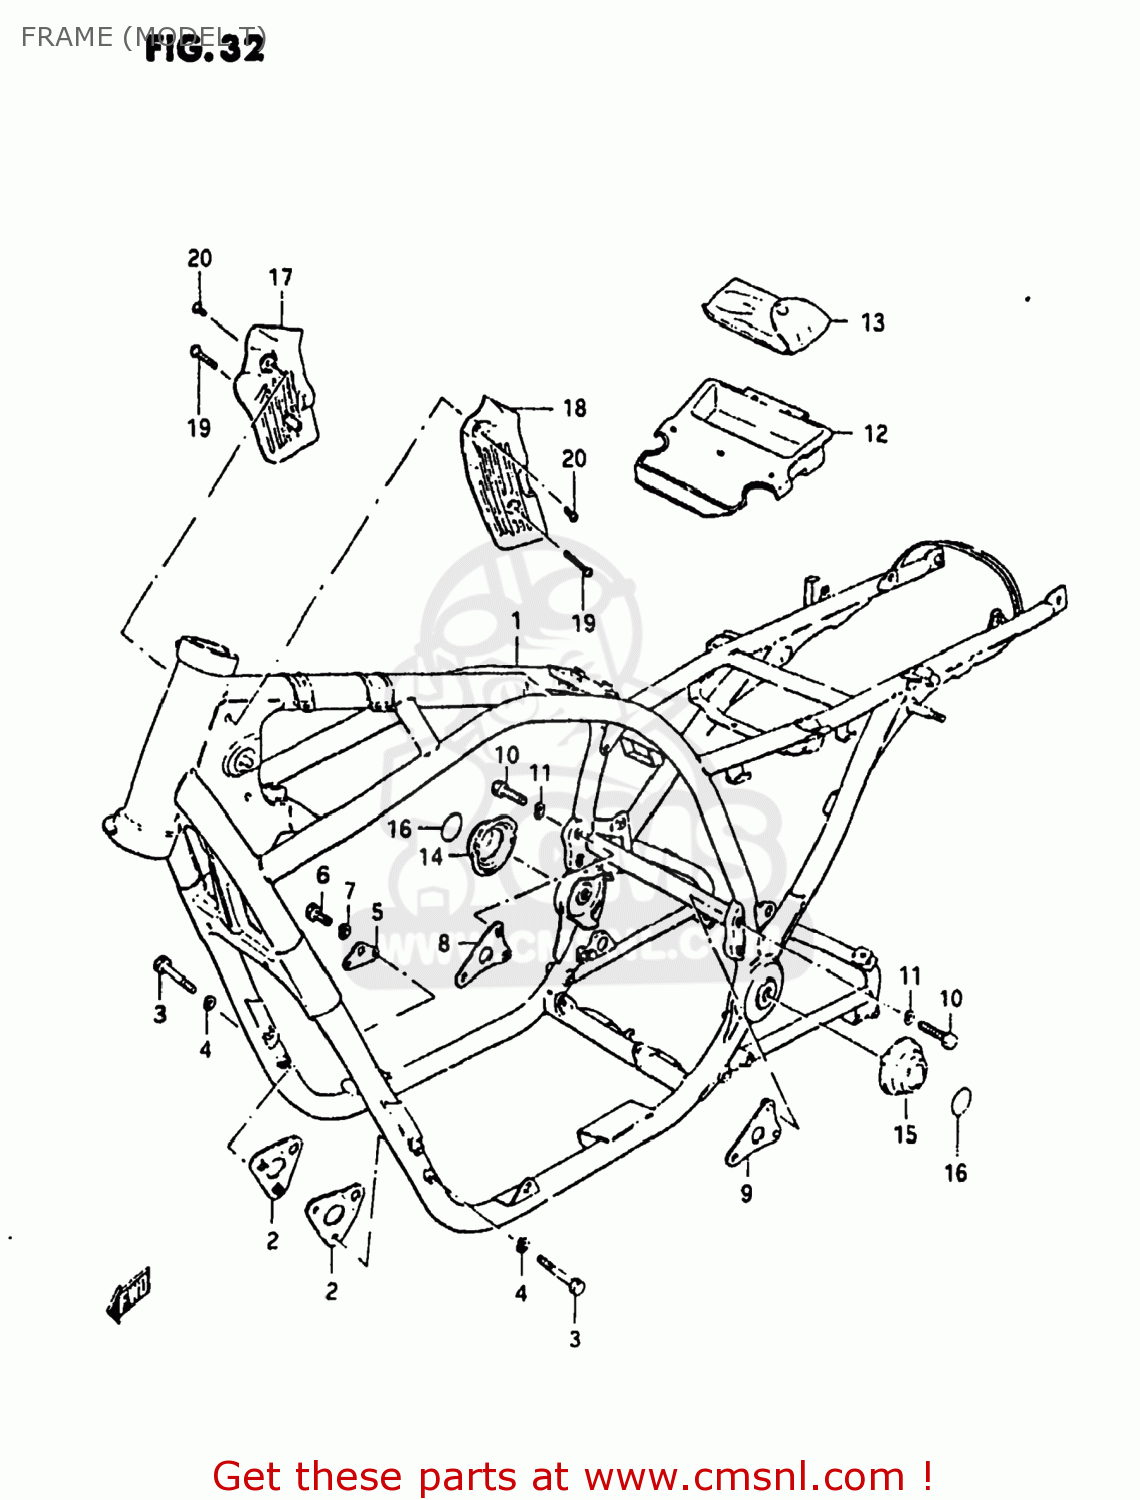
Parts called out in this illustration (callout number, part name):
1	FRAME
2	PLATE,ENGINE MOUNTING
3	BOLT
4	LOCK WASHER
5	PLATE,ENGINE MOUNTING
6	BOLT
7	LOCK WASHER
8	PLATE,ENGINE MOUNTING
9	PLATE,ENGINE MOUNTING
10	BOLT 8X40
11	LOCK WASHER
12	HOLDER,TOOL
13	TOOL SET
14	COVER,REAR SWING ARM PIVOT
15	COVER,REAR SWING ARM PIVOT
16	TAPE,REAR SWING ARM PIVOT
17	COVER,FRAME HEAD,RIGHT
18	COVER,FRAME HEAD,LEFT
19	SCREW, LOWER
20	SCREW
